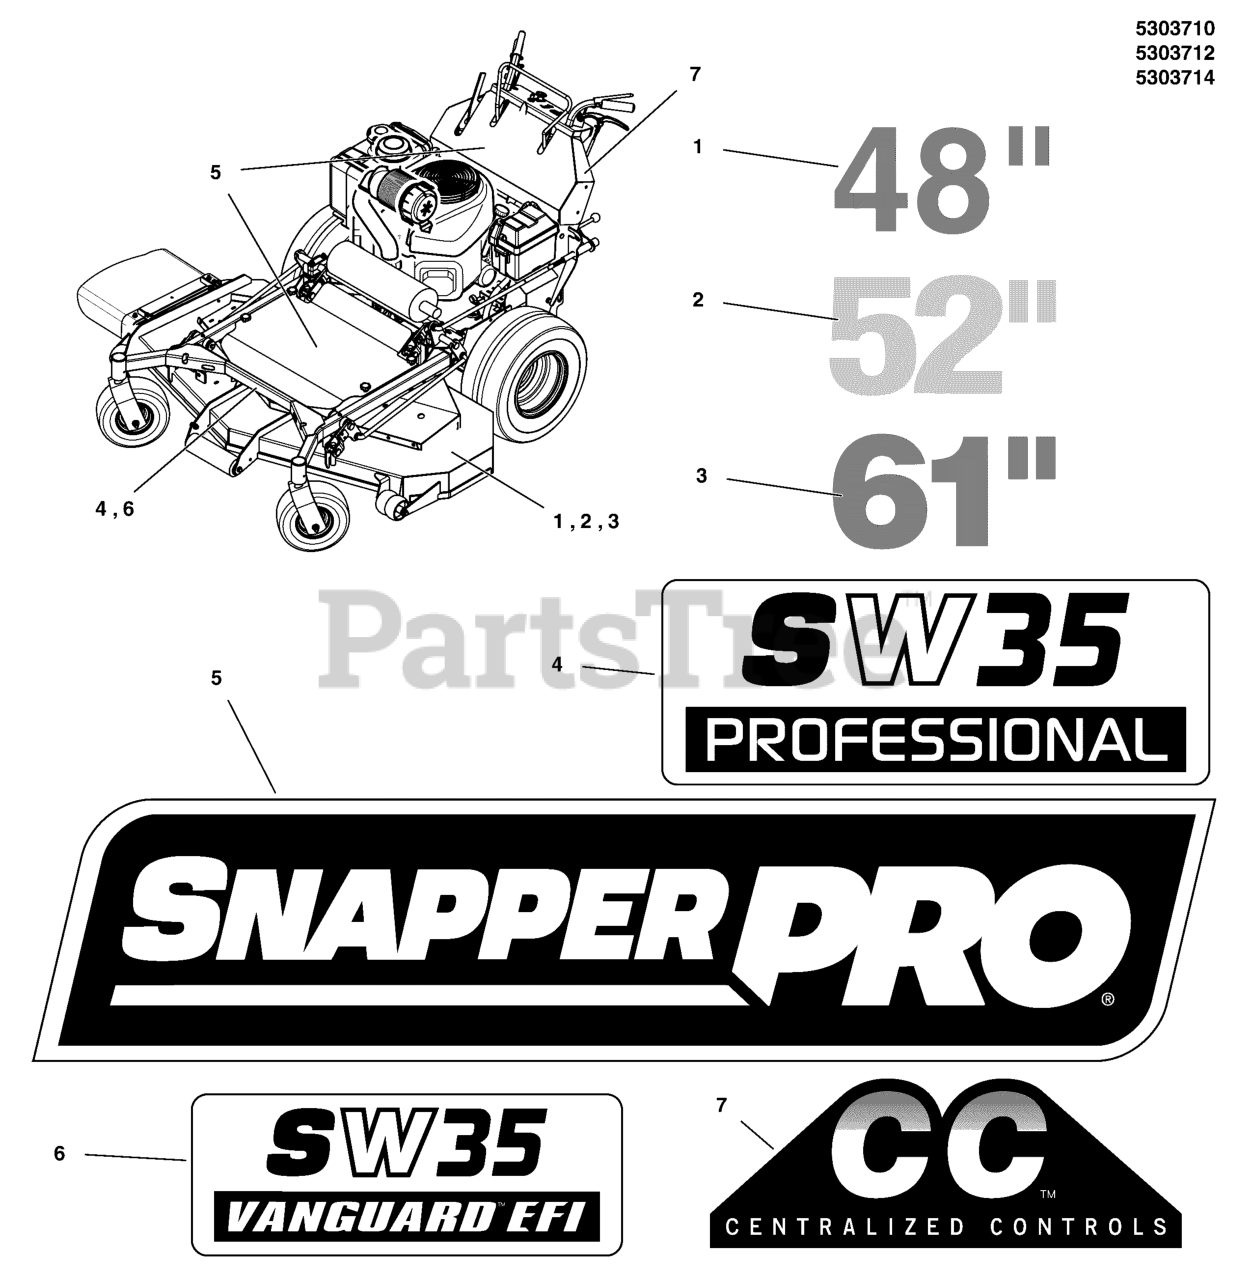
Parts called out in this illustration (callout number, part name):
1	DECAL, 48
2	DECAL, 52
3	DECAL, 61
4	DECAL, BRAND, SW35
5	DECAL, SNAPPER PRO LOGO, LARGE
6	DECAL, MODEL SERIES, SW35, EFI
7	DECAL, CENTRALIZED CONTROLS
